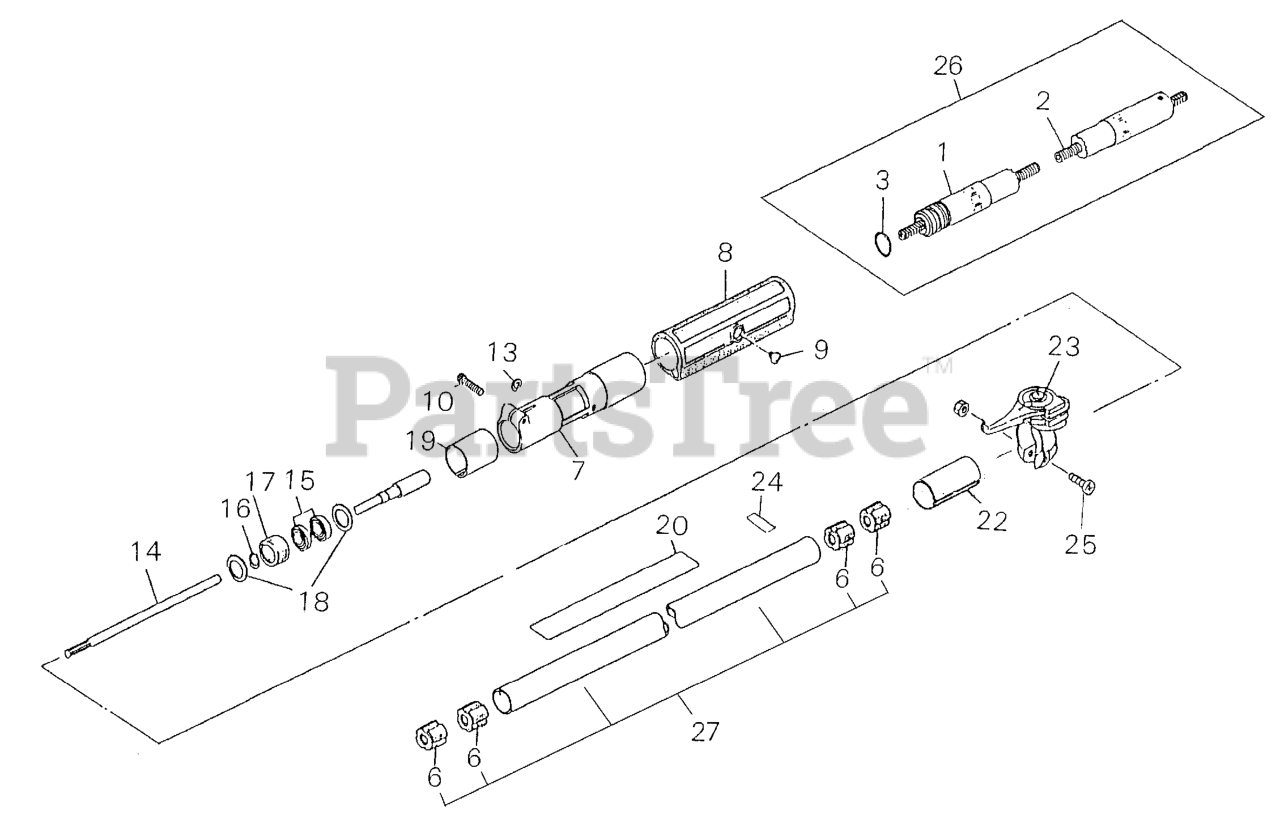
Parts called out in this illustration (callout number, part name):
1	PIPE, MAIN - FLEXIBLE
2	DRIVESHAFT - FLEXIBLE
3	O-RING
6	BUSHING
7	CONNECTOR
8	GRIP
9	SCREW
10	SCREW - 6X28
14	DRIVESHAFT
15	BEARING, BALL - 6900Z
16	RING, RETAINING - 10
17	CUSHION
18	PLATE, THRUST
19	COLLAR
20	LABEL - CAUTION
22	SPACER
23	LEVER, THROTTLE
24	LABEL - ALIGNMENT
25	SCREW - 5X12
26	MAIN PIPE ASSY
27	MAIN PIPE ASSY
29	LABEL - CAUTION
